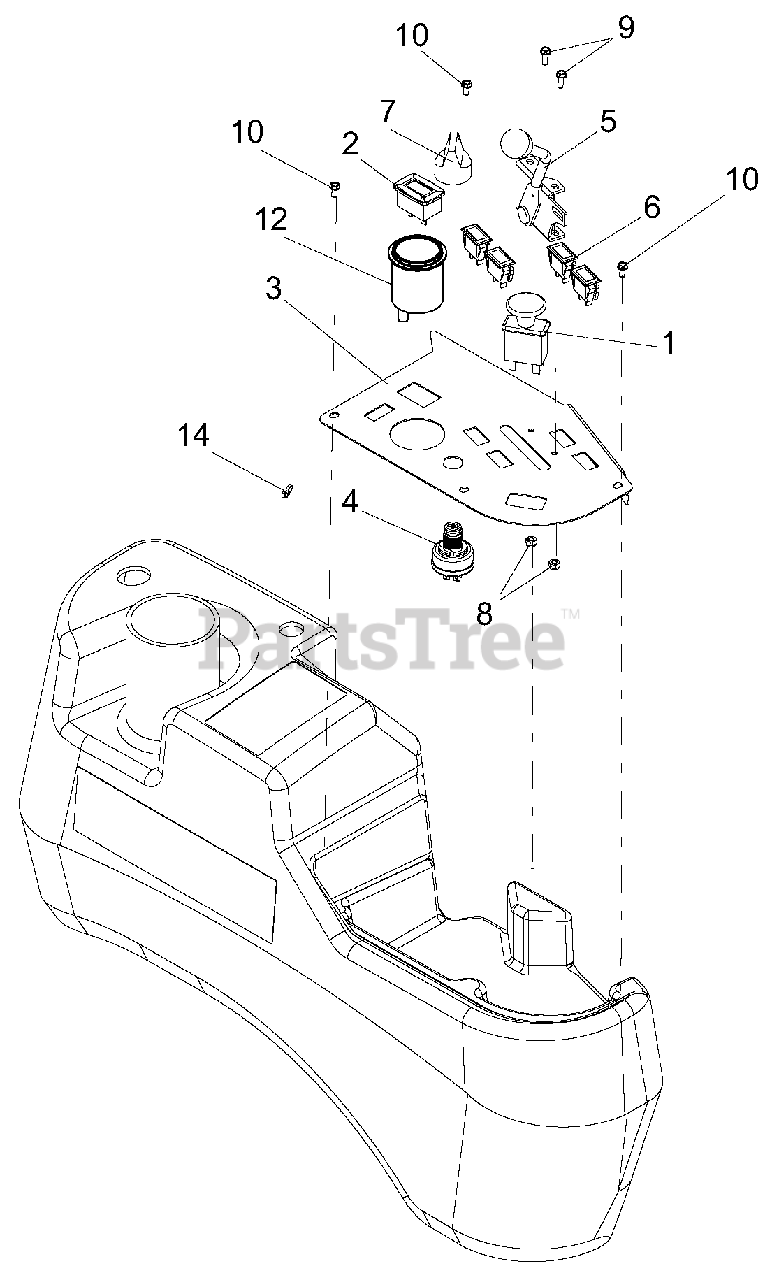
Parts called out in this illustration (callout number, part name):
1	SWITCH, CLUTCH
2	METER, HOUR W/MAINTENANCE
3	PANEL, CONTROL PM 200 DIESEL
4	SWITCH, IGNITION
5	CABLE, PRO-CONTROL THROTTLE
6	LIGHT, INDICATOR
7	KEY, W/ COVER
8	NUT-LK-NYL #10-24 YWZC
9	SCR-MCH 10-24X.50 HWH YWZC
10	SCR, HWH 10-24x.38 STAINLESS
12	GAUGE, TEMP
